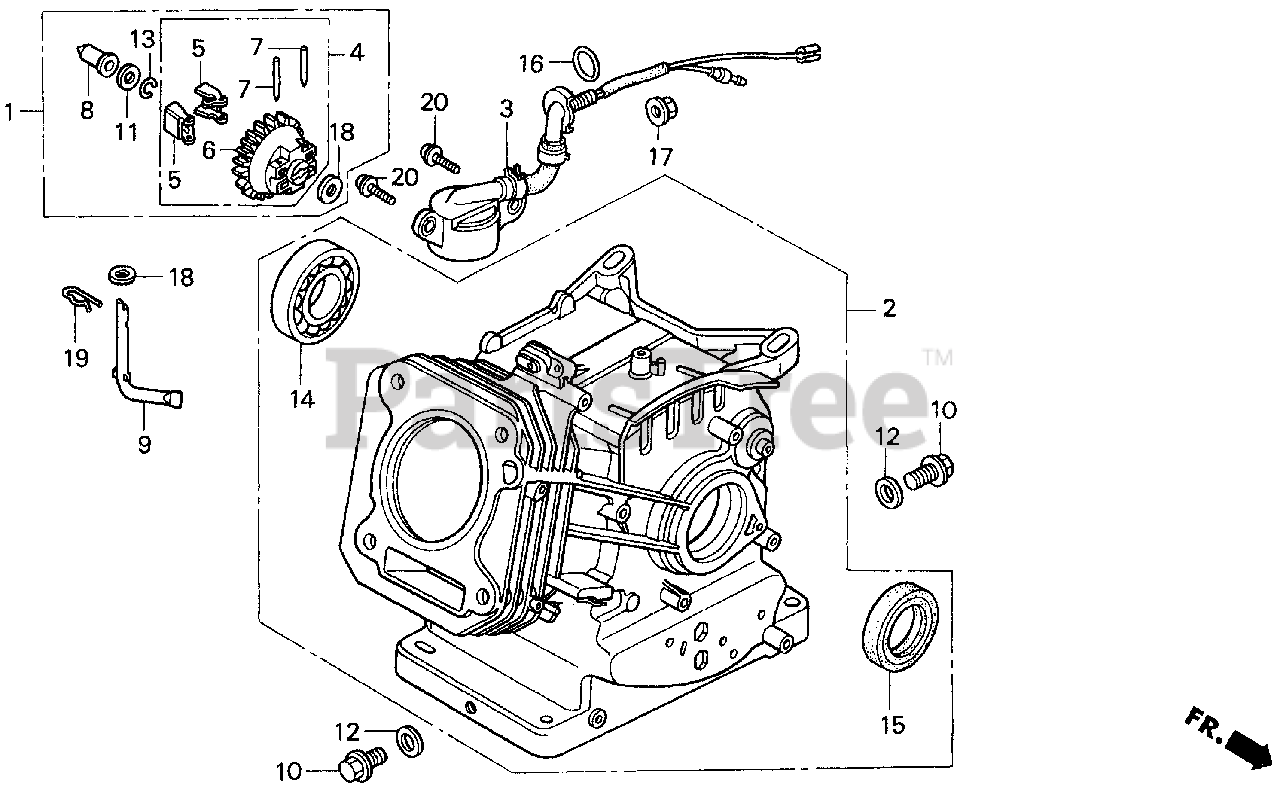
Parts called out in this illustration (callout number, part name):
1	GOVERNOR KIT
2	CYLINDER ASSY.
3	SWITCH ASSY., OIL LEVEL
4	GOVERNOR ASSY.
5	WEIGHT, GOVERNOR
6	HOLDER, GOVERNOR WEIGHT
7	PIN, GOVERNOR WEIGHT
8	SLIDER, GOVERNOR
9	SHAFT, GOVERNOR ARM
10	BOLT, DRAIN PLUG
11	WASHER, THRUST (6MM)
12	WASHER, DRAIN PLUG (10.2MM)
13	CLIP, GOVERNOR HOLDER
14	BEARING, RADIAL BALL
15	OIL SEAL (22X35X6)
16	O-RING (14MM) (ARAI)
16	O-RING (14MM) (NOK)
17	NUT, FLANGE (10MM)
18	WASHER, PLAIN (6MM)
19	PIN, LOCK (8MM)
20	BOLT, FLANGE (6X12)
